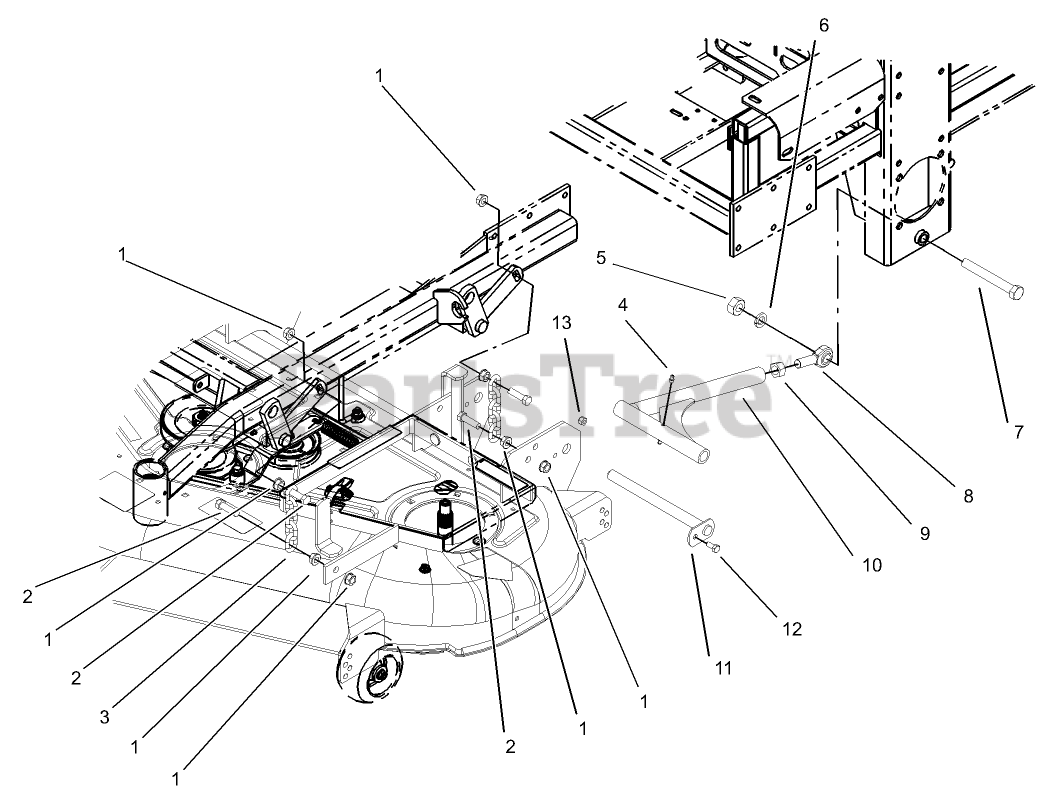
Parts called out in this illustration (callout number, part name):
1	NUT-HF
2	SCREW-CAP, HH
3	CHAIN-LIFT, DECK
4	FITTING-GREASE
5	NUT-HEX
6	WASHER-LOCK
7	SCREW-HH
8	BALLJOINT-SPHERICAL
9	NUT-HEX
10	STRUT
11	PIN-STRUT
12	SCREW-HH
13	NUT-LOCK, NI
